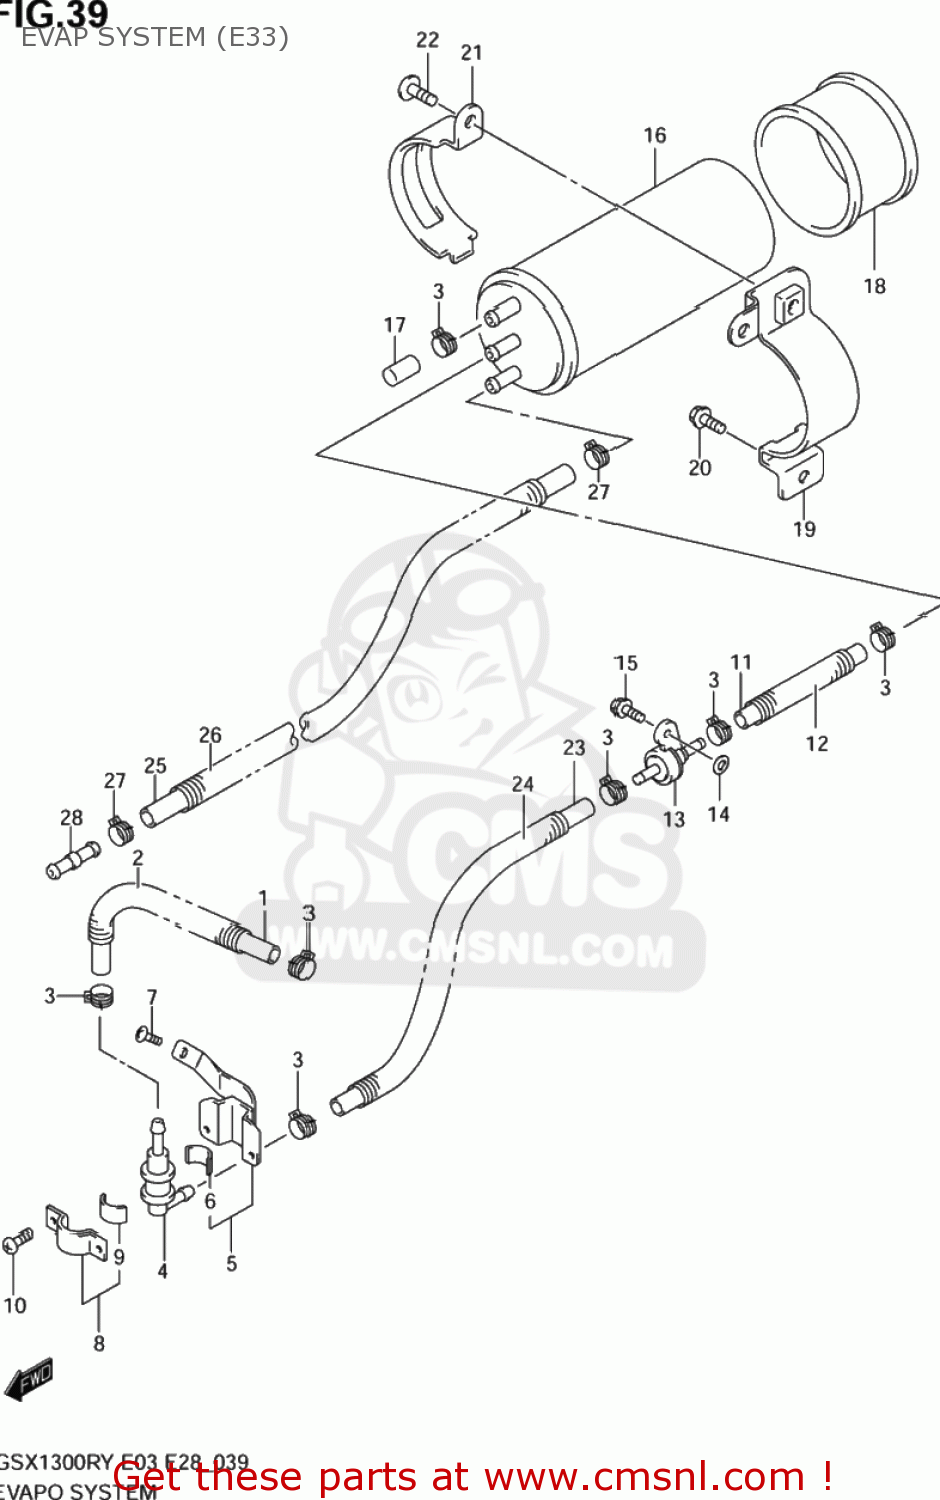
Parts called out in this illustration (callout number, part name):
1	HOSE,TANK & BREATHER VALVE
2	SPRING
3	CLIP
4	VALVE,FUEL TANK BREATHER
5	PLATE,TANK BREATHER VALVE
6	CUSHION
7	SCREW 6X10
8	PLATE,FUEL TANK BREATHER NO.2
9	CUSHION
10	SCREW
11	HOSE(5.4X11.4X600)
12	SPRING
13	VALVE,2 WAY & BREATHER VALVE
14	WASHER(6.5X20X1.2)
15	BOLT
16	CANISTER ASSY,CHARCOAL
17	CAP,OD:11.5
18	CUSHION,CANISTER
19	BRACKET,CANISTER
20	BOLT
21	HOLDER,CANISTER
22	SCREW 6X10
23	HOSE(5.4X11.4X600)
24	SPRING
25	HOSE(5.4X11.4X600)
26	SPRING
27	CLIP
28	UNION
